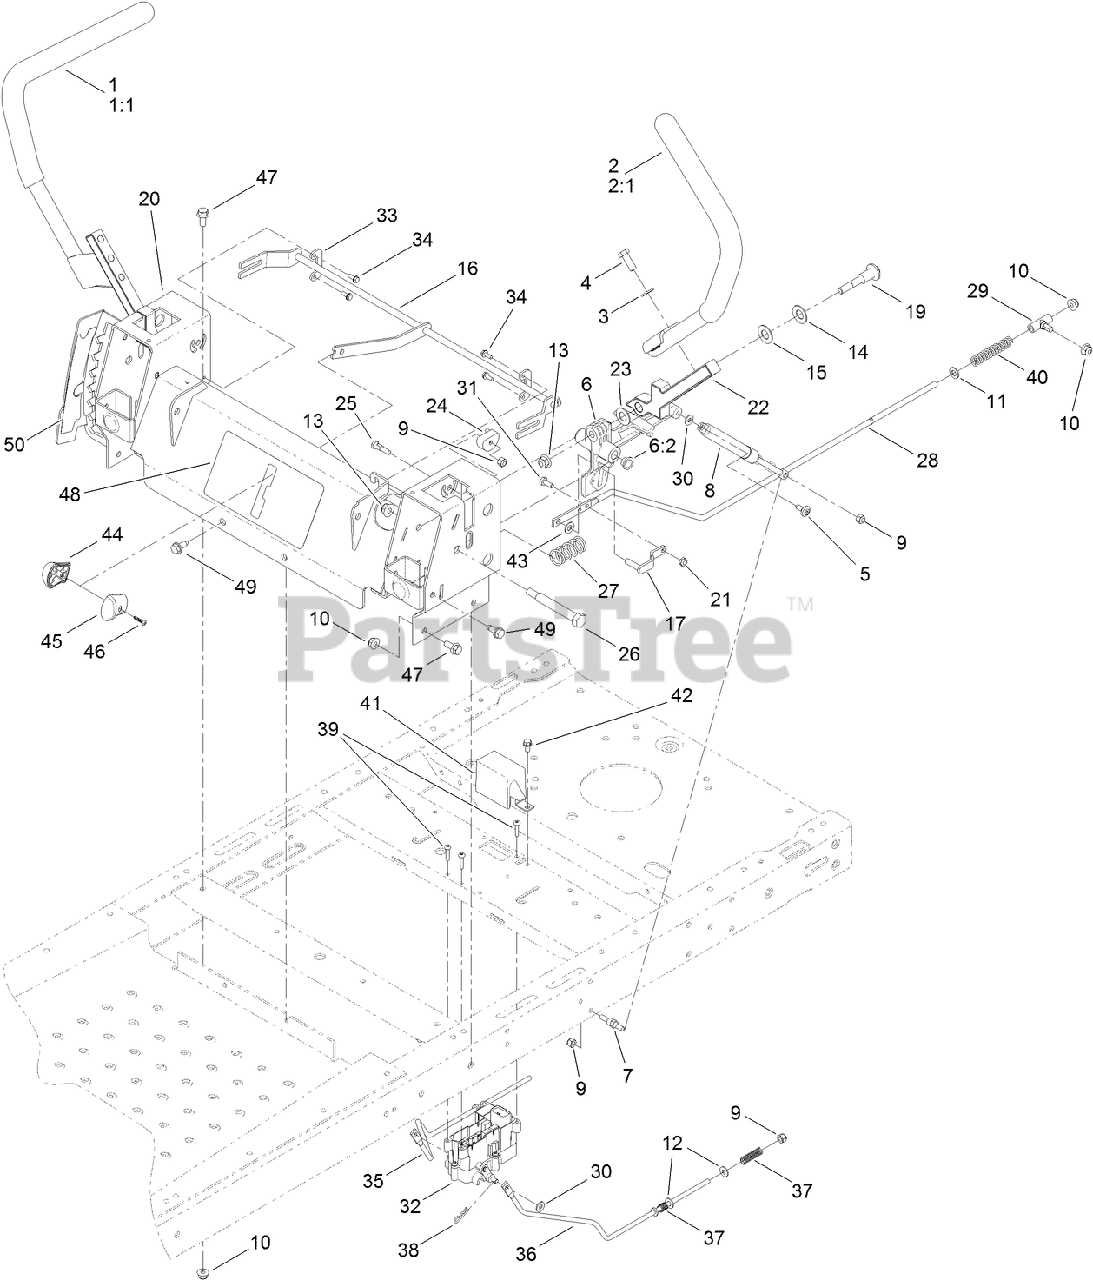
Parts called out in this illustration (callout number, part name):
1	RH HANDLE ASM
2	LH HANDLE ASM
3	WASHER-FLAT
4	SCREW-HH
6	ACTUATOR ARM ASM
6:2	BUSHING-FLANGE
7	STUD-DAMPER
9	NUT-LOCK, NI
10	NUT-HF, NI
11	WASHER-PLAIN
12	WASHER-FLAT
13	NUT-HF, NI
14	WASHER-BELLEVILLE
15	WASHER
16	CONTROL-SPEED
19	BOLT-PIVOT
21	NUT-LOCK, NI
23	WASHER-NYLON
24	ECCENTRIC
25	BOLT-PIVOT, ECCENTRIC
26	BOLT-PIVOT
27	SPRING-RETURN
28	ROD-HYDRO
29	MOUNT-ROD, HYDRO
30	WASHER
31	SCREW-HH
33	RETAINER
34	SCREW-TAPTITE
37	SPRING-COMPRESSION
39	SCREW-PPH
40	SPRING-RETURN, NEUTRAL
41	COVER-BRAKE
42	SCREW-HWH
43	SPACER-NYLON
46	SCREW-PPH
47	SCREW-HHF
48	DECAL-SPEED CONTROL
49	SCREW-HWHTF
50	DECAL-HOC
